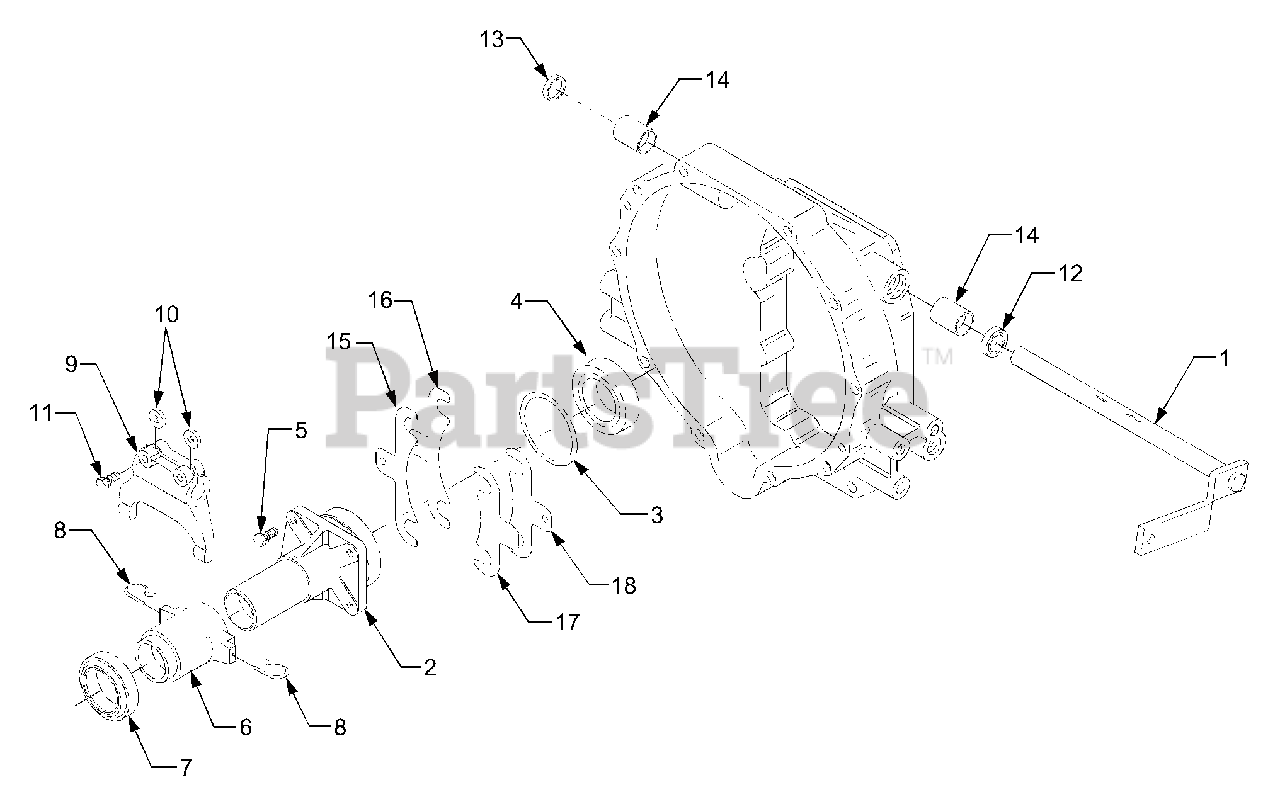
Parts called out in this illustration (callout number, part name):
1	Lever, Main Clutch
2	Case, Propeller Shaft
4	Seal, Oil
6	Hub, Clutch Release
7	Bearing, Release
9	Fork, Clutch Release
